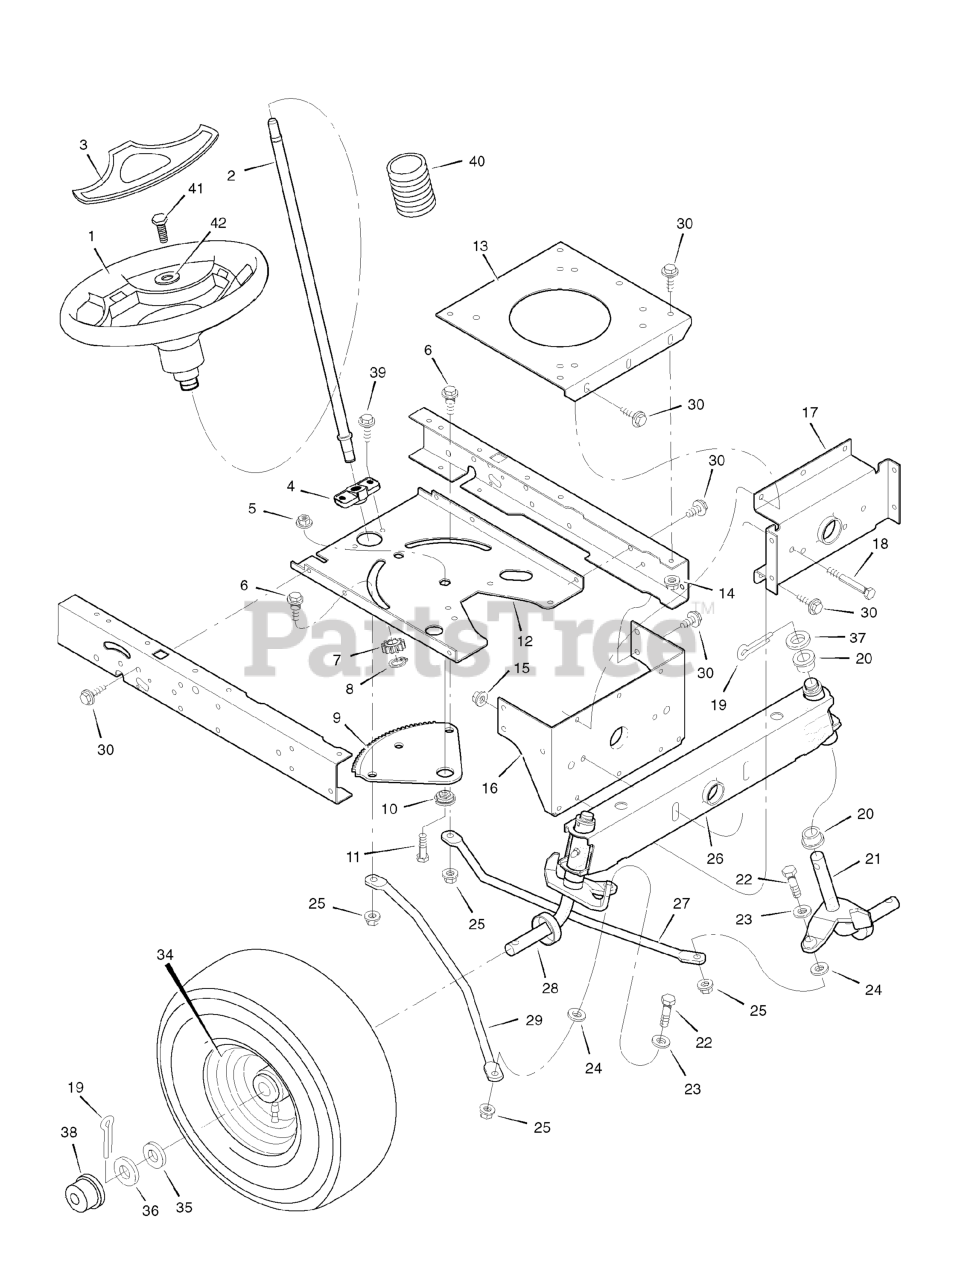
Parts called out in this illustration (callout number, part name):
1	Wheel, Steering
2	Post, Steering
3	Insert, Steering Wheel
4	Bearing, Lower
5	Nut, Flange
6	Bolt, Shoulder
7	Gear, Pinion
8	Ring, Snap
9	Gear, Sector
10	Bearing
11	CAPSCREW, Hex Head, 5/16-18 x 1
12	Plate, Steering
13	Plate, Engine
14	Nut, Flange
15	Nut, Flange
16	Bracket, Hanger
17	Axle, Hanger
19	Pin, Cotter
20	Bearing
21	Spindle Assembly, Left
22	Bolt
23	Washer
24	Washer
25	Nut, Flange
26	Axle Assembly
27	Drag Link, Left
28	Spindle Assembly, Right
29	Drag Link, Right
34	Wheel and Tire Assembly
38	Hub Cap
40	Bellows
41	Screw, Hex
42	Washer
